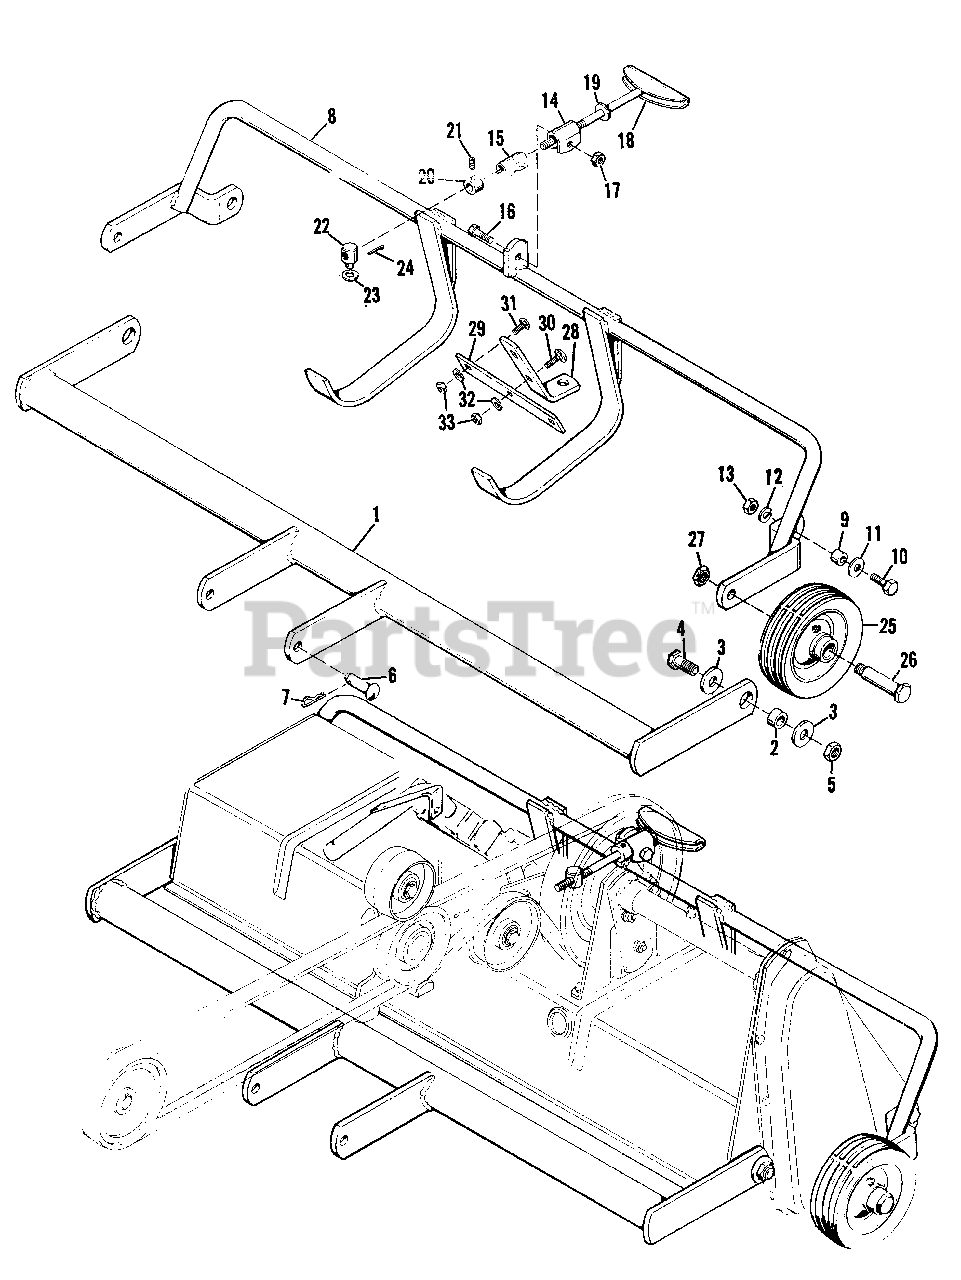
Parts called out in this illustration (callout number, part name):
1	HITCH ASSEMBLY
3	WASHER, Plain, 1/2"
4	CAPSCR EW, Hex 1/2"-13 x 1-1/4" lg.
5	NUT, Hex, Full Lock, 1/2"-13
7	CLIP, Spring
8	ADJUSTER ASSEMBLY
10	CAPSCREW, Hex 3/8"-16 x 1-1/4" lg.
11	WASHER, Plain, 3/8"
12	LOCKWASHER, 3/8"
13	NUT, Hex, Full, 3/8"-16
15	LINER, Guide
16	CAPSCREW, Hex 5/16"-18 x 1-1/4" lg.
17	NUT, Hex, Full Lock 5/16"-18
18	ADJUSTING SCREW ASSEMBLY
19	WASHER, Plain, 3/8"
20	COLLAR, Set
21	SCREW, Set 1/4"-20 x 5/16" lg.
23	WASHER, Plain, 5/16"
24	PIN, Cotter 3/32" x 3/4" lg.
25	WHEEL & TIRE ASSEMBLY
26	BOLT, Wheel
27	NUT, Hex, Full Lock 7/16"-14
29	REINFORCER,Tow Bar
30	BOLT, Carriage 5/16"-18 x 1" lg.
31	BOLT, Carriage 5/16"-18 x 3/4" lg.
32	LOCKWASHER, 5/16"
33	NUT, Hex, Full 5/16"-18
